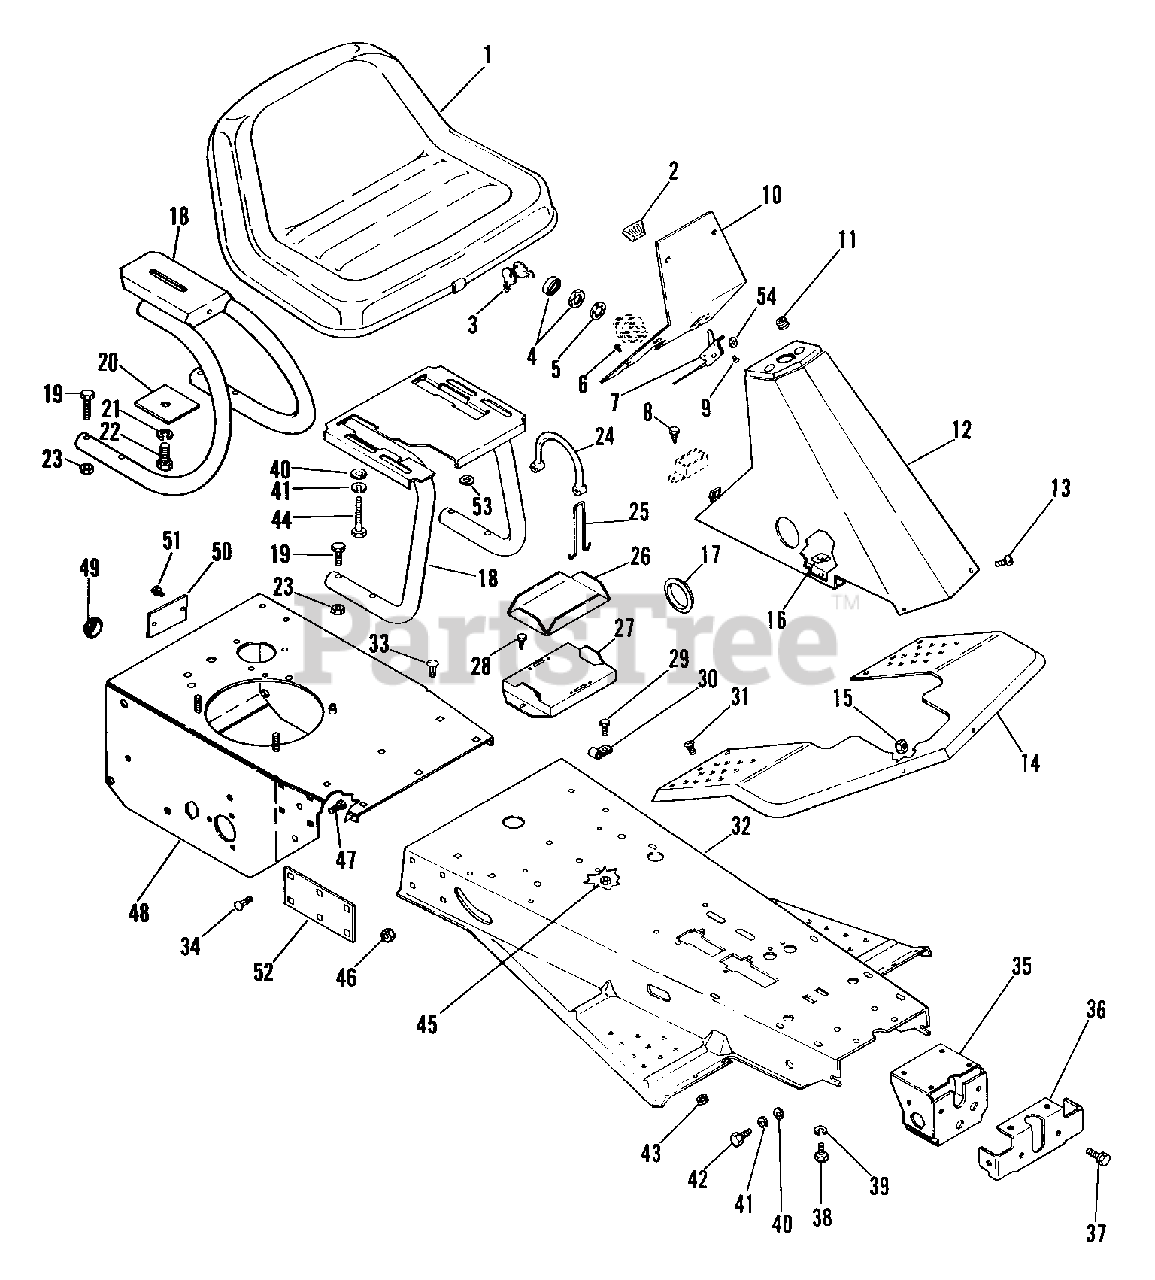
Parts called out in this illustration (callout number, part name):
3	KEYS
4	NUT .625-32 ALUM
5	WSHR-LK-INT .625X.045 PL
6	SCR-TAP 10-12X.50 CRPH PL A
7	THROTTLE CONTROL
8	SCR-TAP 10-24X.375 HWH PL TR
9	RVT-POP.125 X .294 DOME
10	DASH PANEL-FM
11	PLASTIC GROMMET
12	STEERING COLUMN
13	SCR-MCH 10-24X.38 SLTOR PAN PL
14	FRONT FENDER
15	NUT-LK TOP 10-24 PL
16	NUT-SPEED U-TY .312-18
18	SEAT BRACKET
18	SEAT BRACKET WELDMENT
19	BLT-HEX .31-18X1.50 PL GR2
20	SEAT SUPPORT WASHER
21	WSHR-LK .500X.151 HVY PL
22	BLT-HEX .50-13X1.25 PL GR2
23	NUT-LK .312-18 GR A PL
24	BATTERY STRAP
25	HOOK
26	RUBBER PAD
27	BATTERY RETAINER
28	SCR-TAP 10-12X.50 CRPH PL A
29	BLT-HEX .25-20X.50 PL GR2
31	SCR-SLTR-SERNK .25-20X.62 PL
32	FRONT FRAME ASSEMBLY
33	BLT-RDHDSQSHNK .31-18X.50 YZ
34	BLT-RDHDSQNK .31-18X1.00 PL
35	AXLE SUPPORT
36	FRONT FRAME SUPPORT
37	SCR-TAP .312-18X.75 HWH PL TR
38	SCR-CAP BTHD.31-18X.875 GR5 PK
39	WSHR-LK-INT .313X.030 PL
40	WSHR-FL-STL .38X.875X.083 PL
41	WSHR-LK .312X.097 PL HVY
42	BLT-HEX .31-18X.75 PL GR2
43	NUT-LK-FLG .250-20 PL
44	BLT-HEX .31-18X.75 PL GR5
45	NUT-LK-CTR .250-20 PL
46	NUT-FLG. .312-18 PL
47	BLT-RDHDSQNK .31-18X.75 GR5 PL
48	REAR FRAME
51	SCR-TAP 10-24X.50 CRSLPH PL 1A
52	SPACER
53	WSHR-FL-STL .312X1.62X.13
54	RVT-BURR .125X.505X.048
